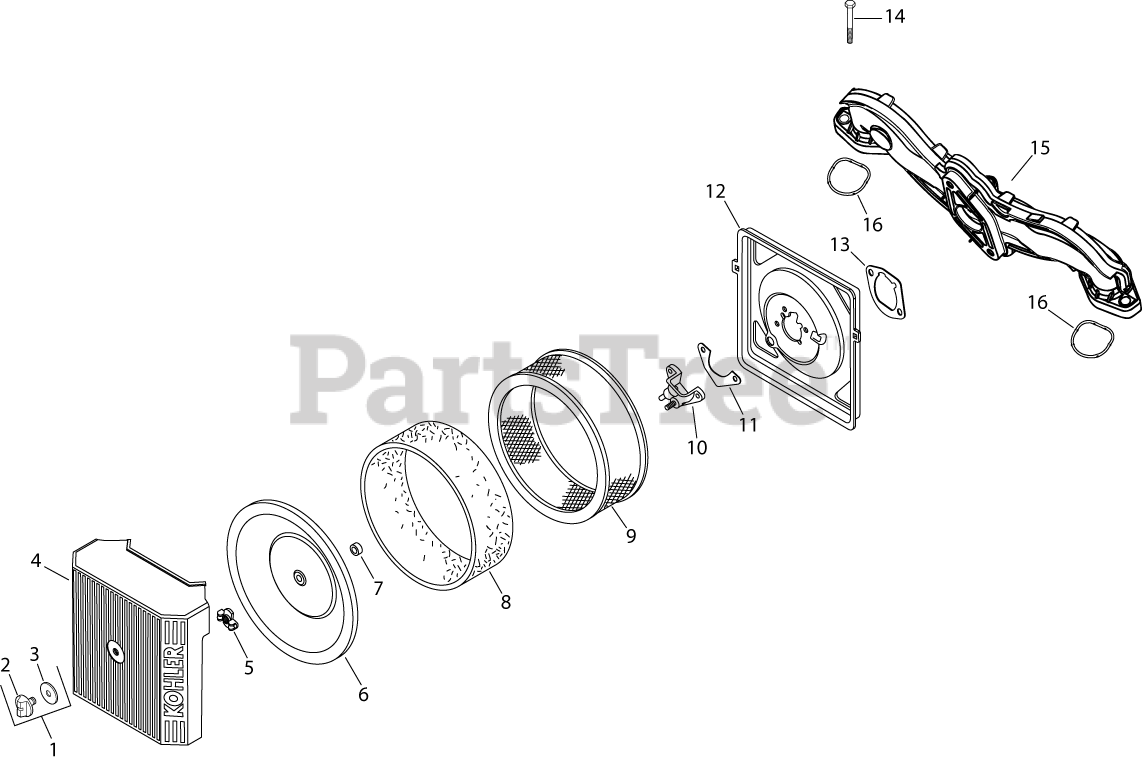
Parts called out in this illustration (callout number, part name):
1	KIT, KNOB W/SEAL
2	KNOB, COVER
4	COVER, AIR CLEANER
5	NUT, WING
6	COVER, INNER AIR CLEANER
7	SEAL, INNER AIR CLEANER
8	ELEMENT, PRECLEANER (LOW)
9	ELEMENT, AIR CLEANER - Also available Retail Packaged 47 883 03-S1 Air Filter Kit
10	CUP, FUEL SPITBACK W/NIPPLE
11	GASKET, FUEL SPITBACK CUP
12	BASE, AIR CLEANER-USE 24 094 87-S
13	GASKET, AIR CLEANER BASE
14	SCREW, FLG M6X1.0X40
15	MANIFOLD, INTAKE
16	GASKET, CARBURETOR
